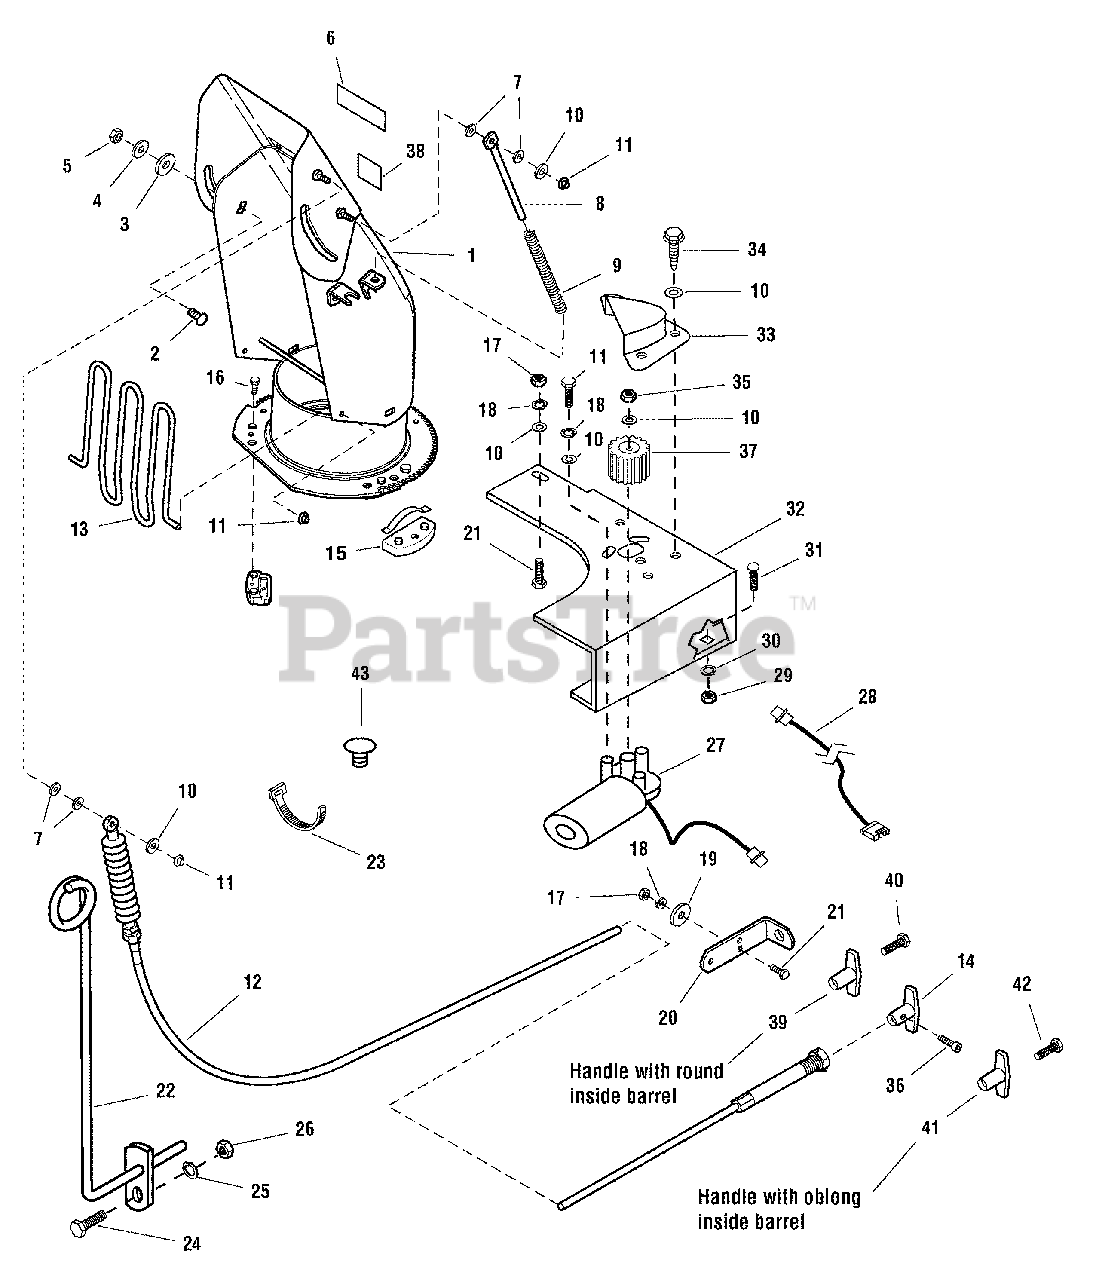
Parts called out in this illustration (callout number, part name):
1	CHUTE ASSEMBLY
2	CARRIAGE BOLT, 5/16-18 x 3/4
3	WASHER, Nylon Special, 3/8
4	WASHER, 5/16
5	NUT, Hex Nylon Lock, 5/16-18
6	SEAL, Hinge, Decal
8	ROD, Spring, 5/16
9	SPRING, Compression
10	WASHER, 1/4
11	NUT, Push, 1/4
12	CABLE ASSEMBLY
13	GUARD, Chute
15	HOLD DOWN, Chute Black Nylon
16	CAPSCREW, Hex Washer Head, Plastite, #10-14 x 5/8
17	NUT, Hex, 1/4-20
18	WASHER, Lock, 1/4
19	WASHER, 1/4
20	BRACKET, Cable Mounting
21	CAPSCREW, Hex Head, 1/4-20 x 7/8
22	GUIDE ASSEMBLY, Cable
23	TIE, Self-Locking
24	CAPSCREW, Hex Head, 5/16-18 X 1
25	LOCKWASHER, 5/16
26	NUT, Hex, 5/16-18
27	MOTOR, Electric
28	WIRE HARNESS
29	NUT, Hex, 3/8-16
30	LOCKWASHER, 3/8
31	CARRIAGE BOLT, 3/8-16 x 3/4
32	SUPPORT, Motor
33	COVER, Pinion
34	CAPSCREW, Hex Head, Taptite, 1/4-20 x 1/2
35	NUT, Hex Lock,1/4-20
36	SCREW, Set Hex, #10-24 x 3/8
37	GEAR, Pinion
38	DECAL, Danger, Blower
39	HANDLE "T"
40	SCREW, Round Head
41	HANDLE "T"
42	SCREW, #8c x 3/4
43	CAP, Plug Black Poly
